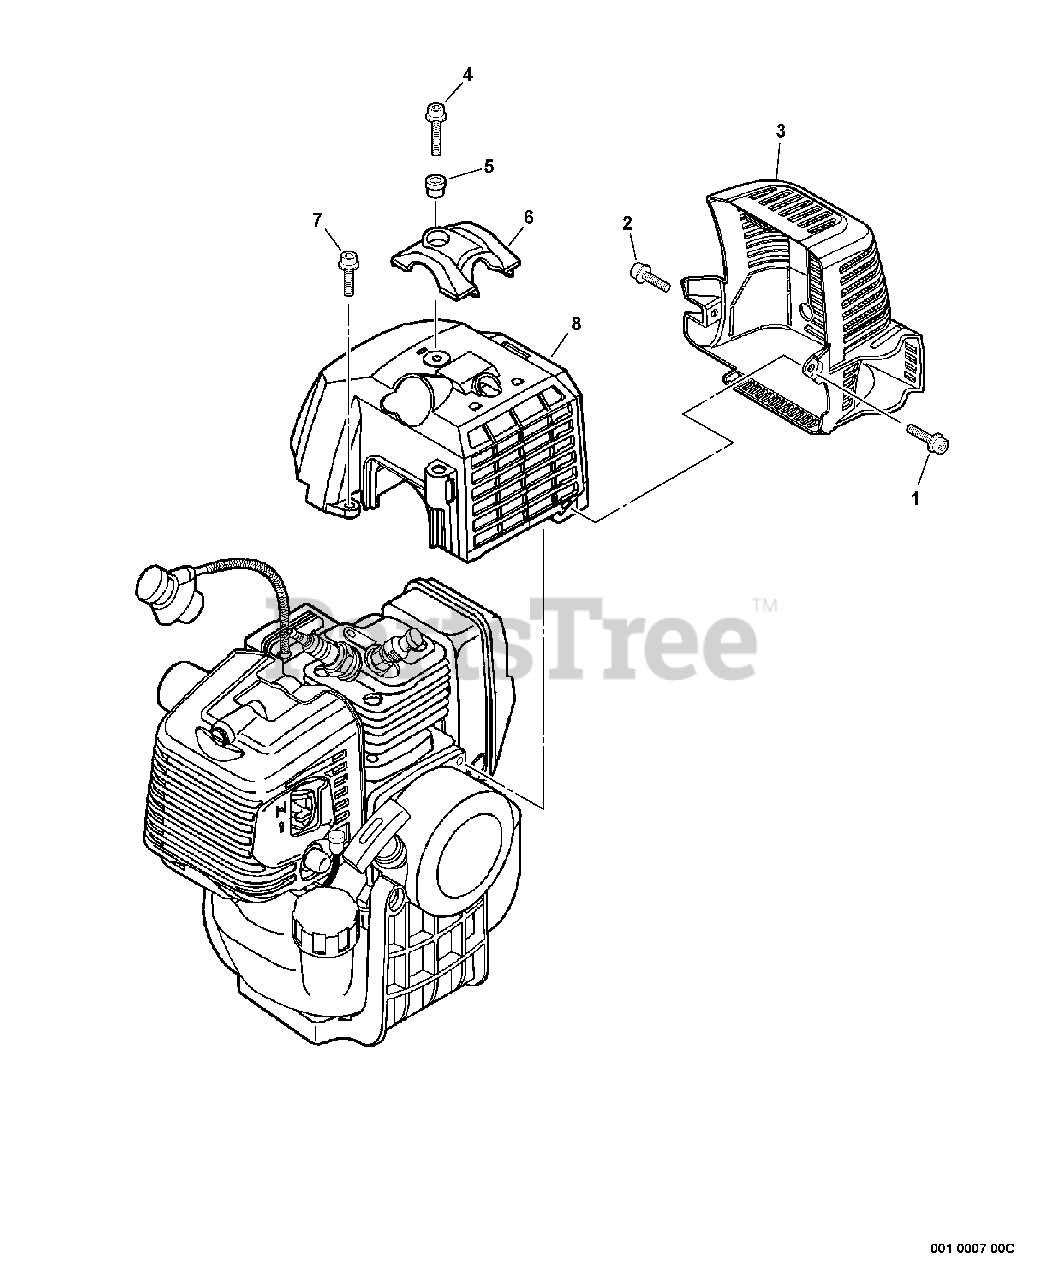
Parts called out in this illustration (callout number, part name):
1	BOLT 5×20
2	BOLT 5×12
3	COVER, MUFFLER
4	BOLT 5×20
5	COLLAR 5
6	GUARD, TOP
7	BOLT 5×12
8	COVER, ENGINE
